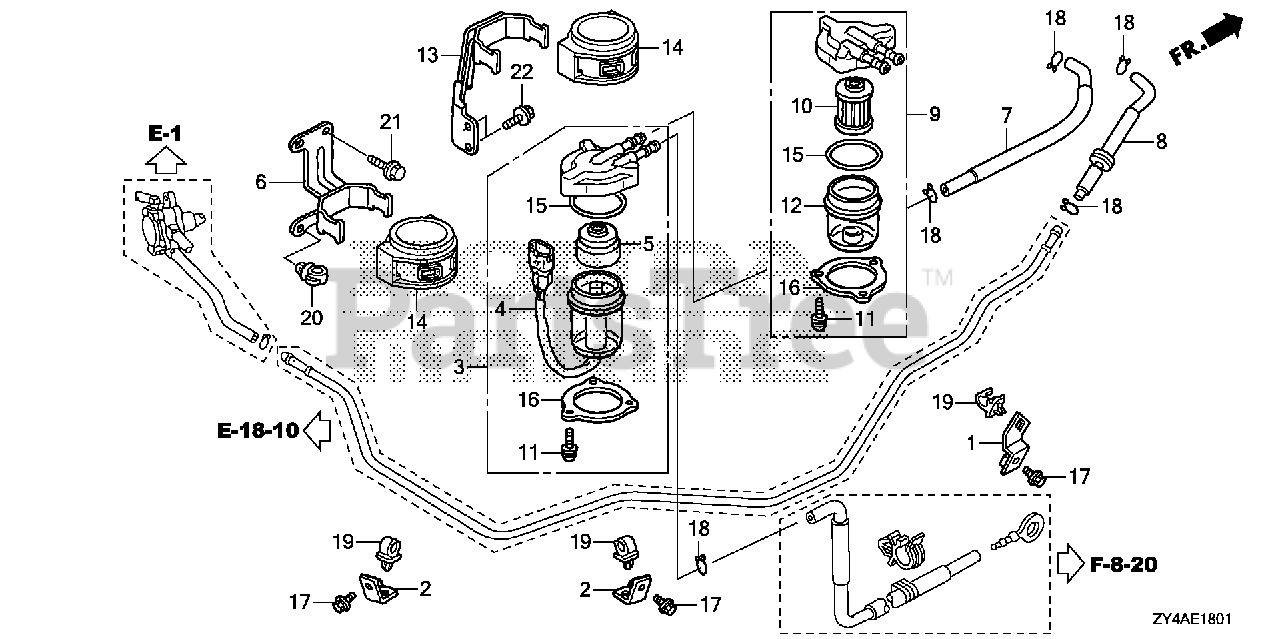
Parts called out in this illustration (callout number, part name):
1	STAY, FUEL PIPE A
2	STAY, FUEL PIPE B
3	SEPARATOR ASSY., WATER
4	CUP, WATER SEPARATOR
5	BUFFER, PLATE
6	STAY, WATER SEPARATOR
7	TUBE, FUEL (B)
8	TUBE, FUEL (C)
9	FILTER, FUEL
10	FILTER, FUEL
11	SCREW, PAN (5X12)
12	CUP, FUEL STRAINER
13	STAY, FUEL STRAINER
14	SUSPENSION, STRAINER
17	BOLT, FLANGE (6X12)
18	CLIP, TUBE (B12)
19	CLAMP, WIRE (8MM)
20	CLIP, WIRE HARNESS (25MM)
21	BOLT, FLANGE (6X10)
22	BOLT, FLANGE (6X14)
